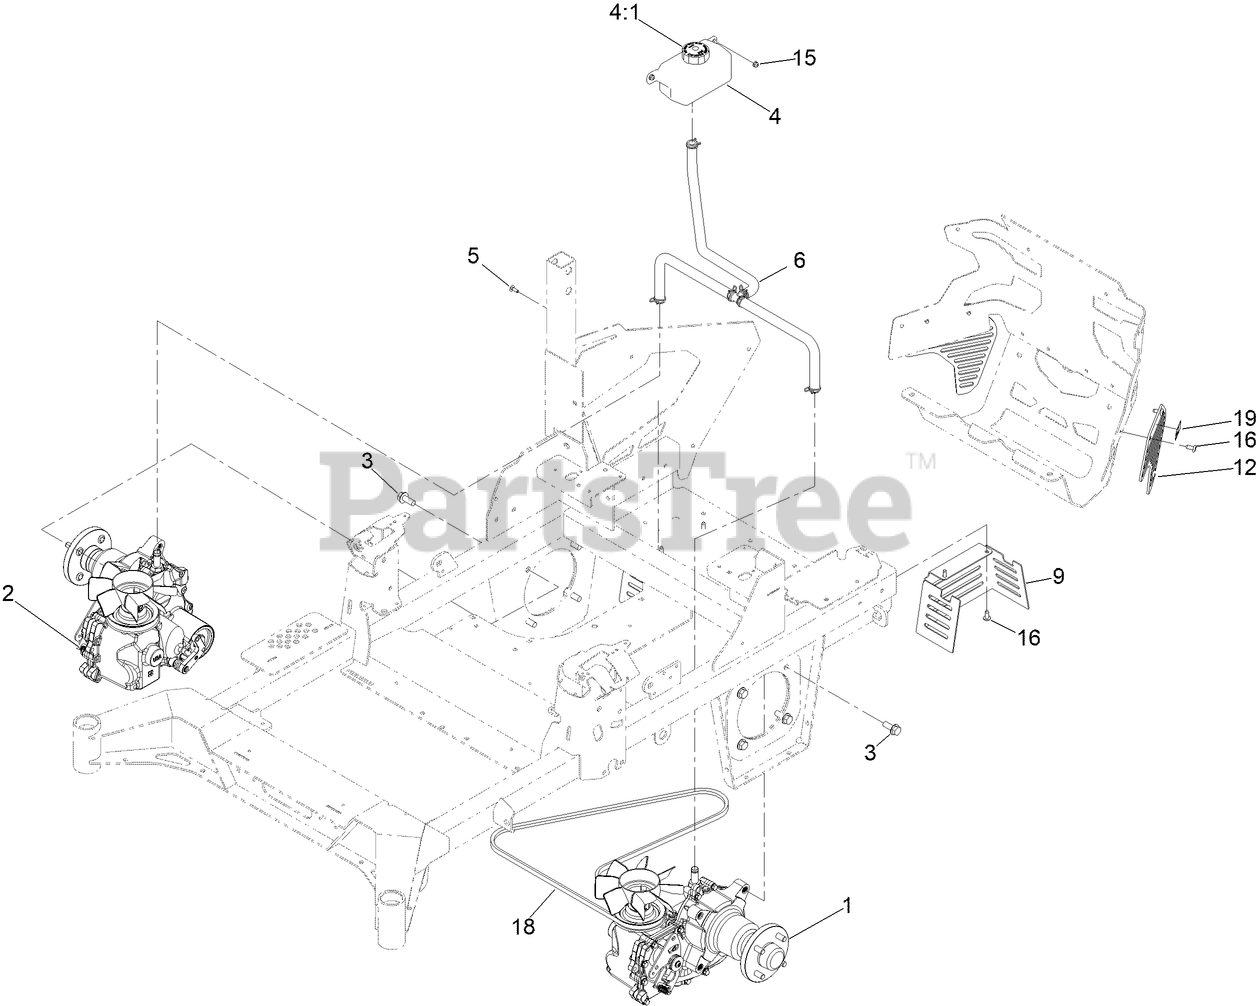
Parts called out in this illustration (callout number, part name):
1	LH TRANSAXLE ASM W/ARM
2	RH TRANSAXLE ASM W/ARM
3	SCREW-HHF
4	HYDRAULIC RESERVOIR ASM
4:1	CAP-RESERVOIR, HYD
5	SCREW-CARR
6	ASM-HOSE, HYDRAULIC
9	GUARD-CLUTCH
12	GUARD-MUFFLER, TE
15	NUT-HF
18	BELT-V
19	DECAL-WARNING
